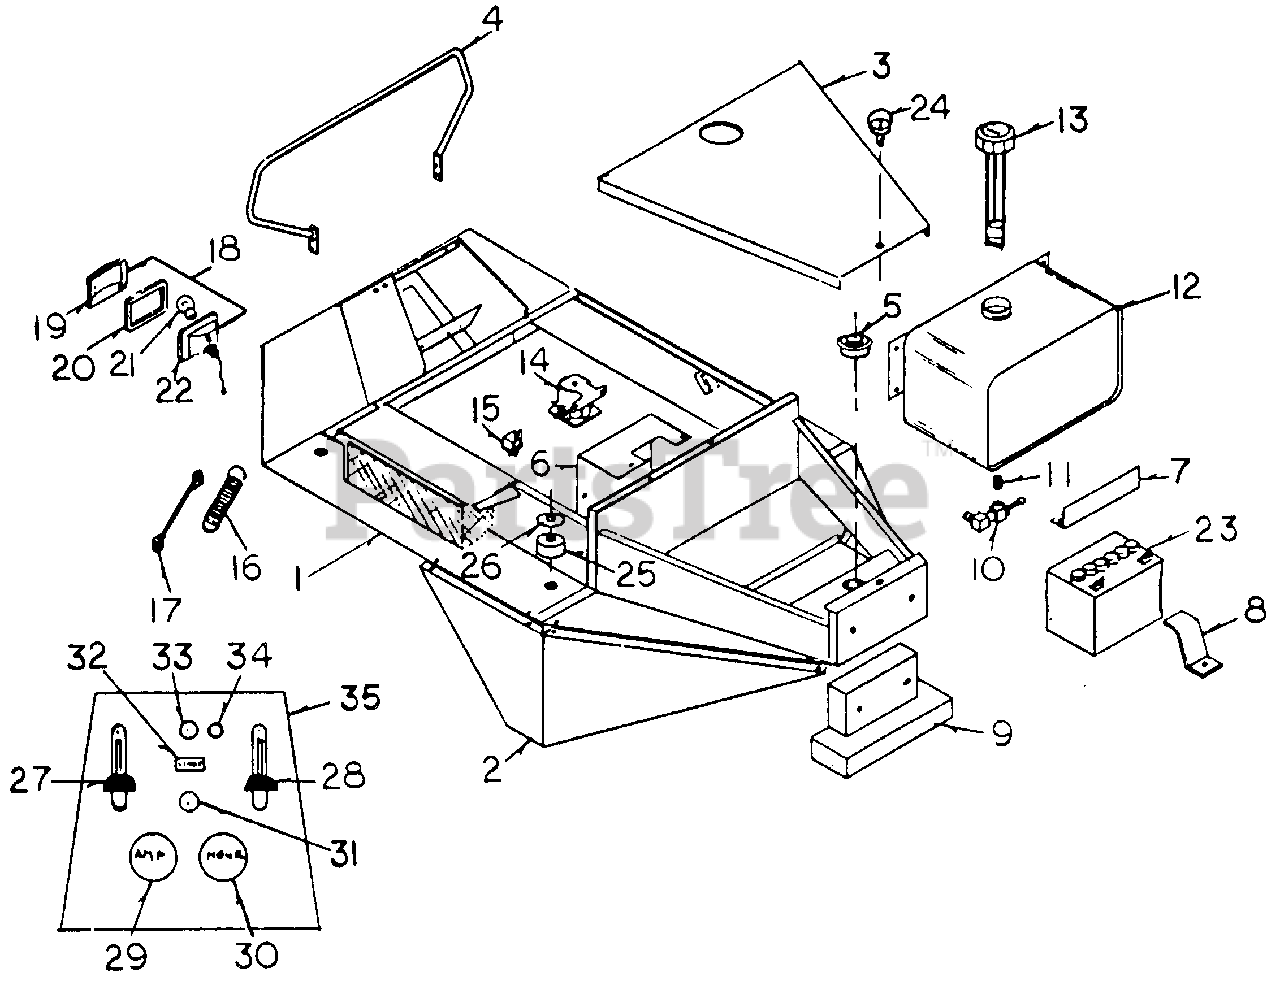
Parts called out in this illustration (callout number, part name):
1	Body
2	Fender, RH
6	Oil Tank Mount
8	Battery Post Protector
10	Shut-off Valve, Fuel
13	Fuel Tank Cap w/Gauge
15	Relay
17	Deck Lift Cable
18	Light Assembly
19	Lens
20	Gasket
21	Bulb
23	Battery
25	Rubber Body Mount
26	Body Mount Washer
28	Throttle Cable
31	lgnition Switch
32	Light Switch
33	Clutch Switch
